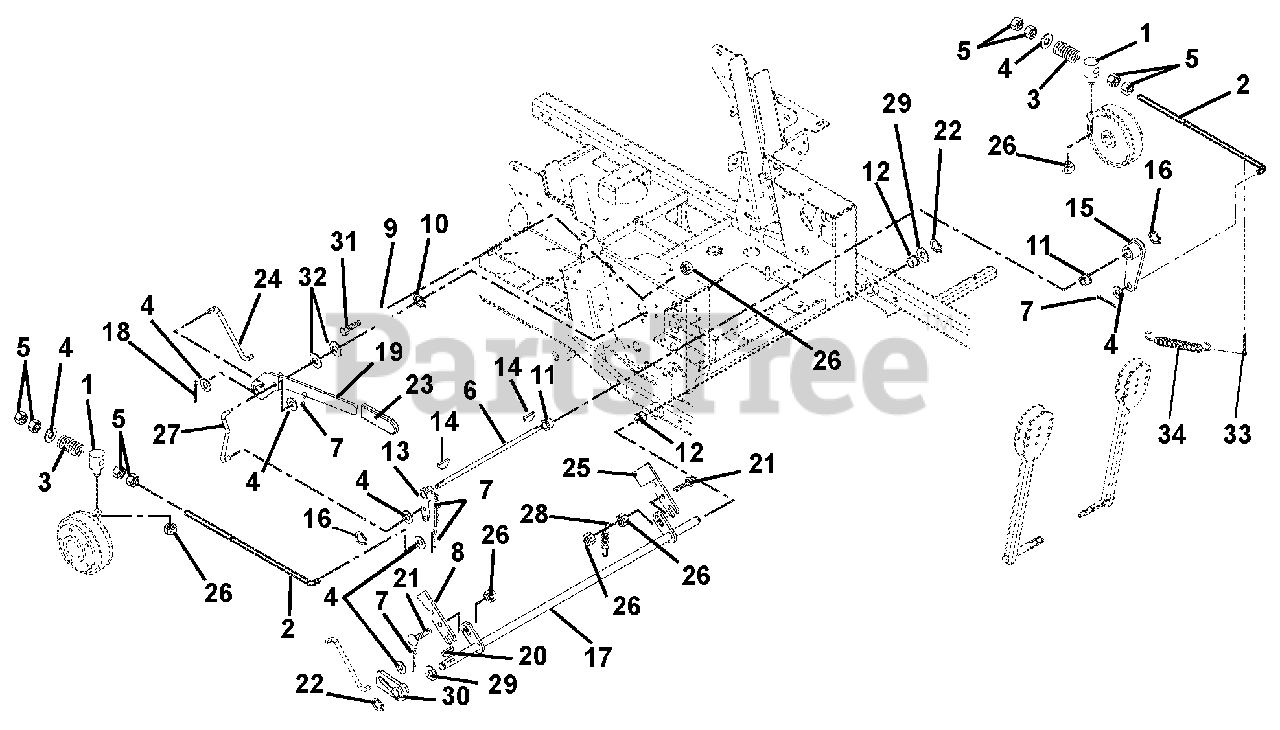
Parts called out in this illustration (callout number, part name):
1	Pivot, Brake Rod
2	Rod, Brake .38 x 19.00 (992212)
3	Spring, Compression .142 x .710 x 1.75
4	Washer, Flat Steel .406 x .812 x .065
5	Nut, Hex .38-16
6	Shaft, Brake 2.00
7	Pin, Hair
8	Slide, Interlocking Brake
9	Bushing, Flange
10	Ring, Retaining External .625 x .05
11	Bushing, Flange Nylon .762 x 1.00 x .58 x 1.48
12	Bushing, Flange .515 x .75 x .745 x 1.00
13	Weldment, 200 Brake ACT. Arm
14	Key-Square .188X1.00X.188 SAE 8630
15	Arm, Brake Left Hand
16	Ring, Retaining External .625 x .050
17	Weldment, Mechanical Brake
18	Pin, Cotter External .09 x .75
19	Weldment, Brake Handle
20	Key, Woodruff .13 x .63
21	Bolt, Round Head Square Neck .31-18 x 1.25 Grade 5
22	Ring, Retaining External .50 x .05
23	Grip, Handle
24	Linkage, Brake Actuating
25	Interlock, Safety Switch
26	Nut, Locking, Top Flange .31-18
27	Linkage, Brake Actuating
28	Spring, Tension .063 x .44 x 1.56
29	Washer, Flat Steel .505 x 1.00 x .062
30	Weldment, Parking Brake Hub
31	Bolt, Hex .31-18 x .75 Grade 5
32	Washer, Flat Steel .630 x 1.250 x .062
33	Pin, Cotter .12 x .75 Extended Prong Square Cut
34	Spring, Extension
